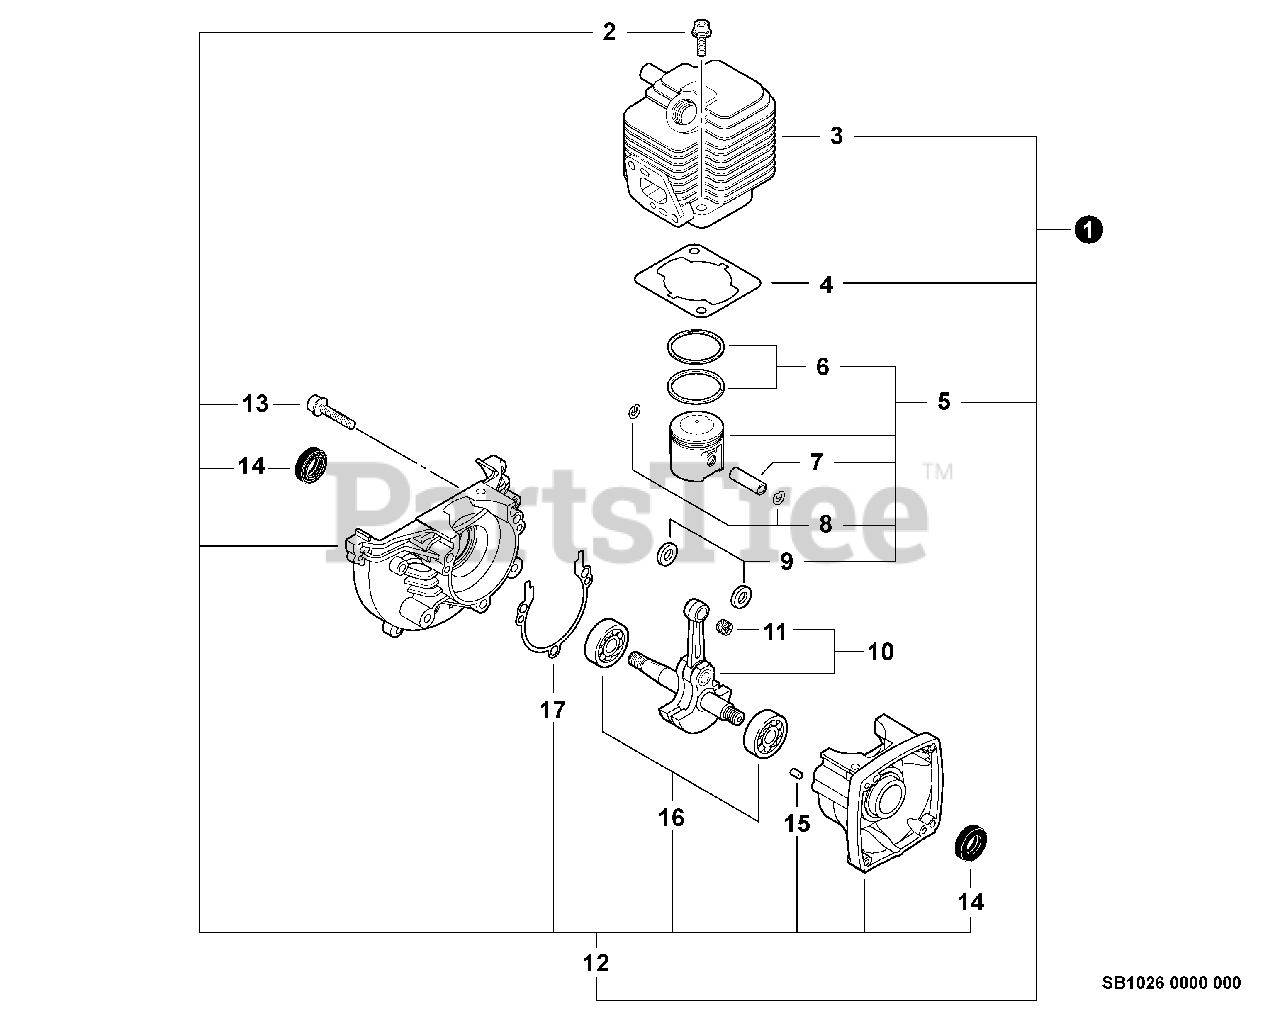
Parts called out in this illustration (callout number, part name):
1	SHORT BLOCK ES-2100;PB-2100
2	CYLINDER
3	BOLT 5×22
4	GASKET, CYLINDER
5	PISTON KIT
6	RING, PISTON
7	PIN, PISTON 8
8	RING, SNAP
9	WASHER, THRUST
10	CRANKSHAFT ASSY
11	BEARING, NEEDLE 8
12	CRANKCASE KIT
13	SEAL, OIL 12
14	PIN, LOCATING 4
15	BEARING, BALL - 6201 C3
16	GASKET, CRANKCASE
17	BOLT 5×28
